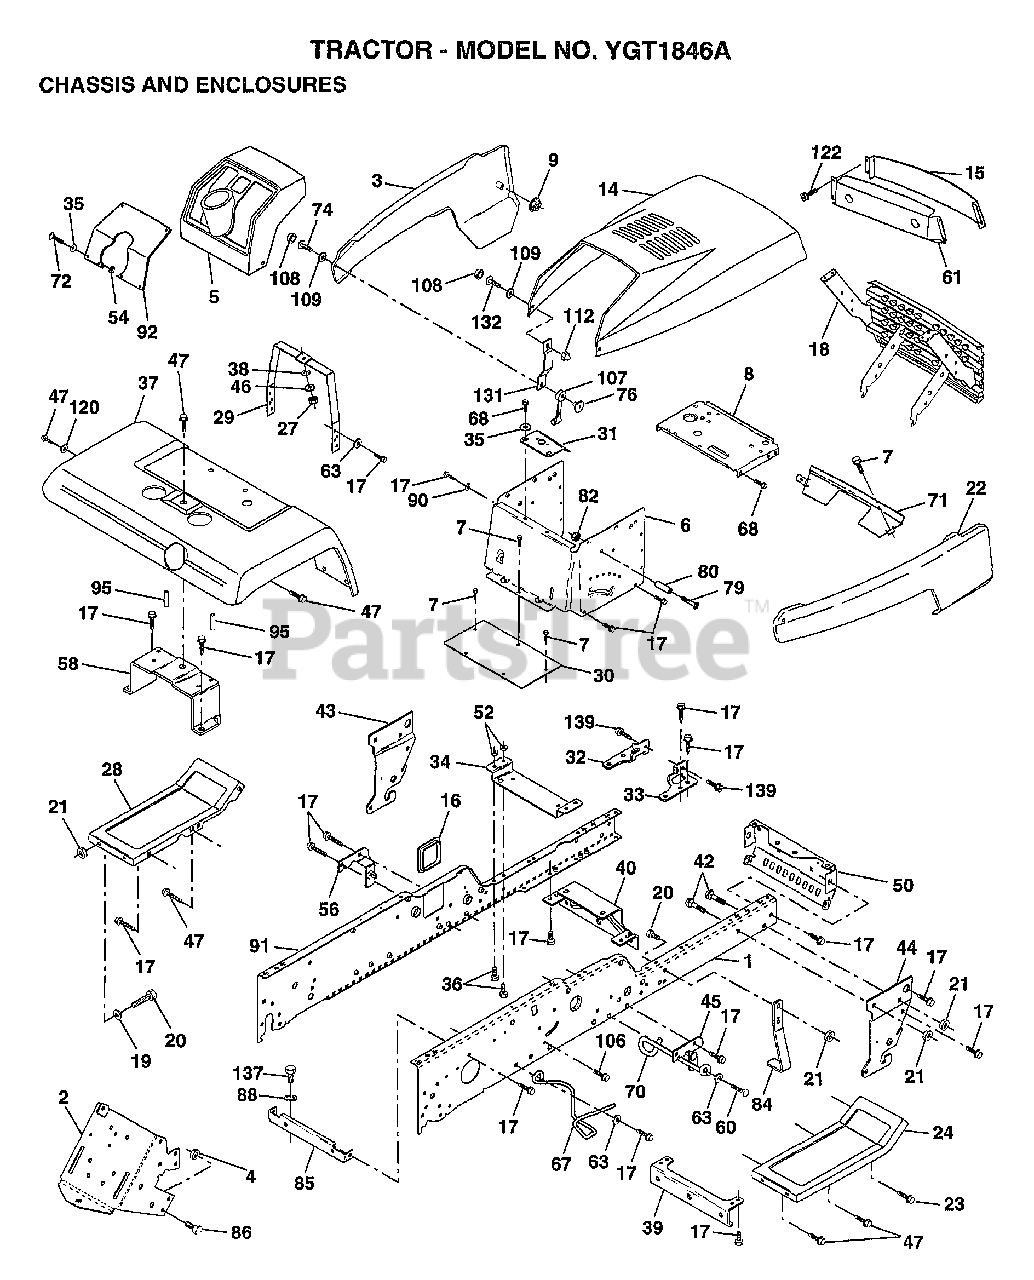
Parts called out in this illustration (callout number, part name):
1	"RAIL,FRAME RH"
2	DRAWBAR GT
3	"PANEL ASM-SIDE,LH"
4	NUT.7/16
5	DASHBOARD BLACK
6	"DASH AS.,LOWER"
7	SCREW
8	SUPPORT.DASH.BTRY
9	PAL NUT LT
14	"HOOD, YARD PRO"
15	LENS.BAR.CLEAR
16	COVER ACCESS
17	SCREW
19	WASHER
20	BOLT
22	"PANEL ASM SIDE,RH"
23	SCREW GTV
24	FOOTREST.RH.LT/GT
28	FOOTREST PNT LH
29	DASH.SUPT.YP/HUSQ
30	SADDLE.SCR.6SP
31	BRKT SUPT 1-PC VG
32	BKRT.PIVOT.CHASSIS.RH
33	BKRT.PIVOT.CHASSIS.LH
34	BRACKET.ENG.SUPT.
35	WASHER
36	BOLT
38	LOCKWASHER
39	BRACKET.AXLE.FRT.
43	BRACKET.SUS.FT.LH
44	BRACKET.SUS.FT.RH
45	BRACKET.SUSP.RH.
46	WASHER PM
47	SCREW LT
50	"BRKT CHASSIS,FRNT"
52	NUT
56	BRACKET.SUSP.LH.
58	BRKT.ASM.FENDER
60	SCREW
61	BEZEL.1 PC
63	WASHER
67	GUIDE BELT TRANS
68	SCREW LT
70	GUIDE.BELT.MID.SP
72	SCREW
74	SCREW
76	WELDNUT
79	SCREW
80	SPACER LT
84	STOP.OVER.CENTER
85	BRACKET.SUPT.TRAN
86	BOLT
88	LOCKWASHER
90	LOCKWASHER
91	"RAIL,FRAME LH"
92	"PLATE DASH,SLKSCR"
95	NUT-PUSH YT
107	HOOD LATCH T
108	SNAP CAP LT
109	WASHER LT
112	NUT, ACORN, HEX
120	WASHER HYT
122	SCREW.HEX.WS.HD
131	BKT.SPT.HOOD/PANL
132	SCREW.10-24X3/8.
137	BOLT.FIN.HEX.
139	BOLT.SHOULDER.5/16-18
